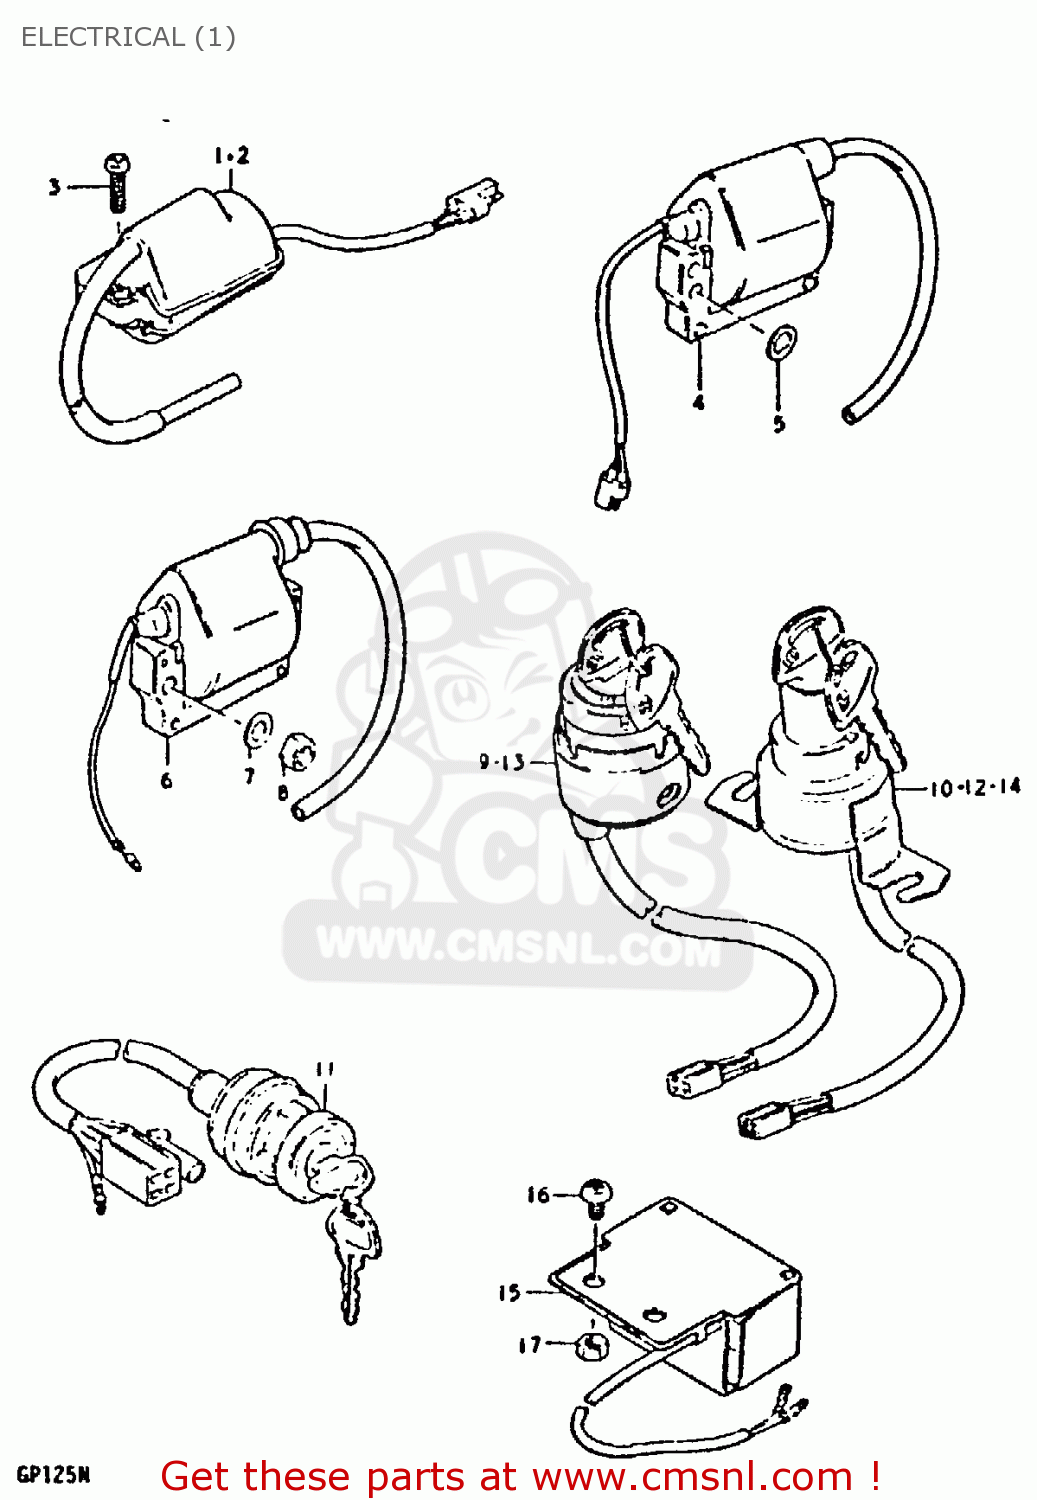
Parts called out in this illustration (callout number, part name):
6	COIL ASSEMBLY,IGNITION
7	WASHER
8	NUT
11	SWITCH ASSY, IGNITION
15	RESISTOR ASSY
16	SCREW
17	NUT
